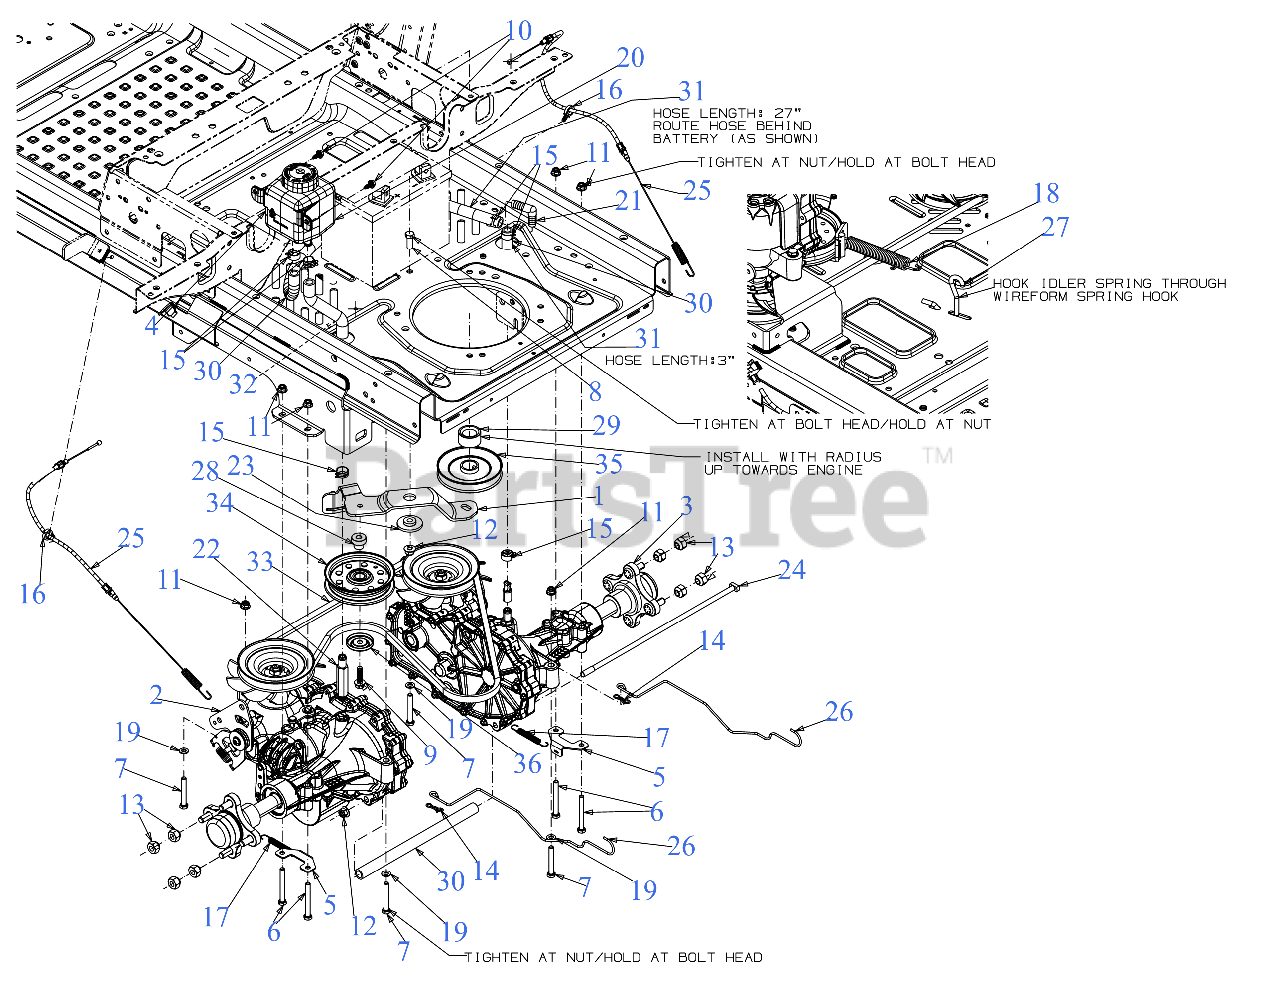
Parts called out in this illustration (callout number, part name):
1	IDLER BRACKET ASSEMBLY
2	TRANSMISSION (LH)
3	TRANSMISSION (RH)
4	HYDRAULIC TANK
6	HEX SCREW 5/16-18 x 2.75
7	HEX SCREW 5/16-18 x 2.25 GR5
8	SCREW 3/8-16 x 1 GR5
9	SCREW 3/8-16 X1.250
10	SCREW 1/4-20X.625
11	FLANGE LOCK NUT 5/16-18
13	LUG NUT 7/16-14
14	BOW TIE COTTER PIN 1/4-5/16
15	FUEL HOSE CLAMP .75
16	CABLE RETAINER CLIP
17	EXTENSION SPRING .38 OD x 3.25 LG
18	EXTENSION SPRING .75 DIA x 5.87
19	FLAT WASHER .344 x .62
21	90 DEGREE NYLON FITTING
22	EXTENSION FITTING 9/16-18
23	SHOULDER SPACER
24	SUPPORT TUBE ROD
25	PARK BRAKE CABLE
26	HYDRO BYPASS ROD
27	IDLER SPRING HOOK
28	SHOULDER SPACER
29	ENGINE PULLEY SPACER
30	TRANSMISSION SPACER .75OD x 11.31
31	FUEL LINE 1/2"ID x 30"
32	EXPANSION TANK HOSE
33	TRANSMISSION DRIVE BELT A x 67
33	Cub Cadet TRANS DRIVE BELT A x 67 RZT
33	Troy-Bilt TRANSMISSION DRIVE BELT
34	IDLER PULLEY 4.25 DIA
35	TRANSMISSION DRIVE PULLEY
36	IDLER PULLEY CAP
